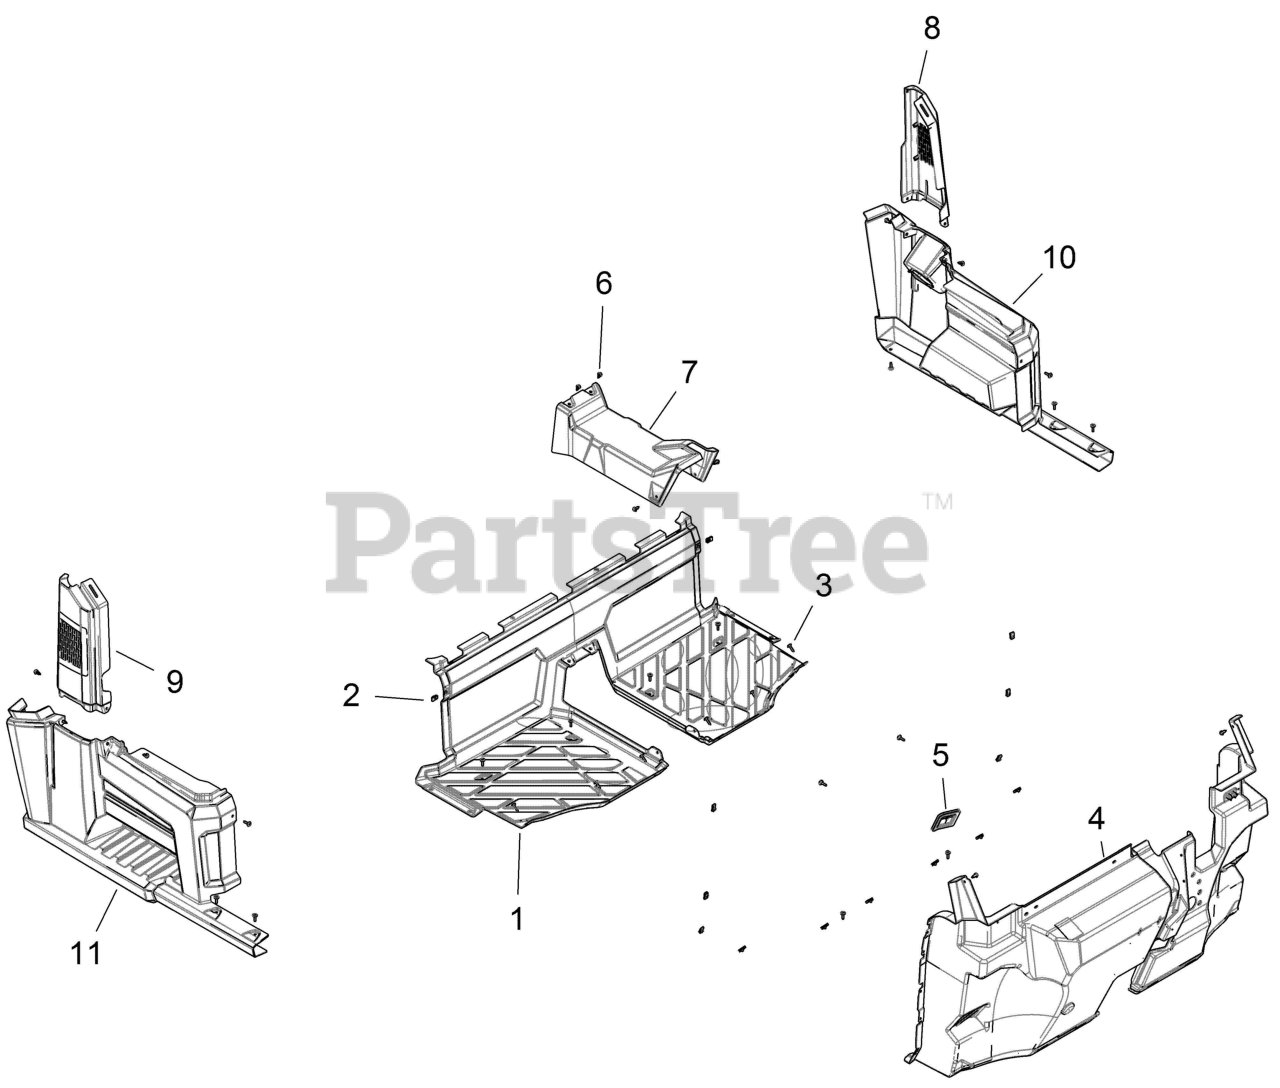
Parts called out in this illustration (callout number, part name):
1	FLOOR-BLK
2	CLIP-U SPEED NUT
3	SCR-TXTH-M6X1.0X25 RIE
4	FLOOR-FRONT,BLK
5	GROMMET-STEERING,FLOOR
6	RIVET-TUFLOK,.315-.325X.787 (5
7	COVER-DRIVE SHAFT,FLOOR,BLK
8	ASM-FENDER-REAR,UPPER,LH,BLK
9	ASM-FENDER-REAR,UPPER,RH,BLK
10	FENDER-REAR,W/ROCKER,LH,ARIENS
11	FENDER-REAR,W/ROCKER,RH,ARIENS
